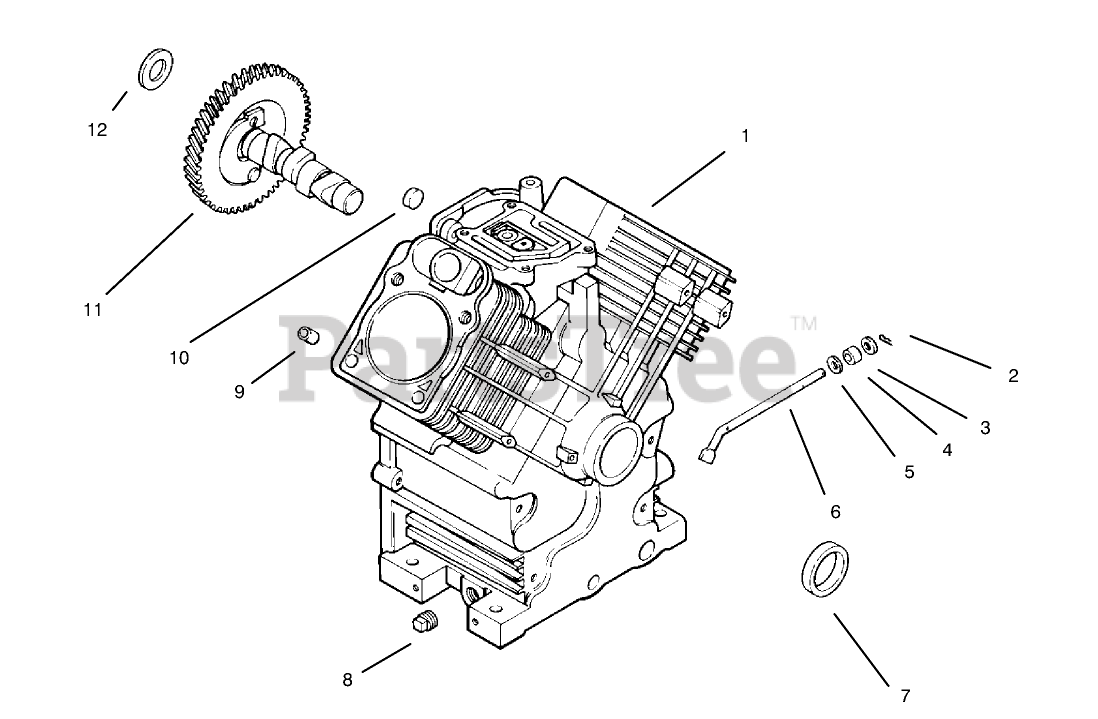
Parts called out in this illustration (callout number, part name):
2	Pin-Hitch
3	WASHER-FLAT (1/4)
4	Seal-Cross Shaft, Governor
5	WASHER-FLAT (1/4)
6	Shaft-Governor Cross
7	SEAL-OIL
8	Plug, Sq. Hd.
9	Pin-Dowel
11	Camshaft
12	SHIM-CAMSHAFT (RED .032)
